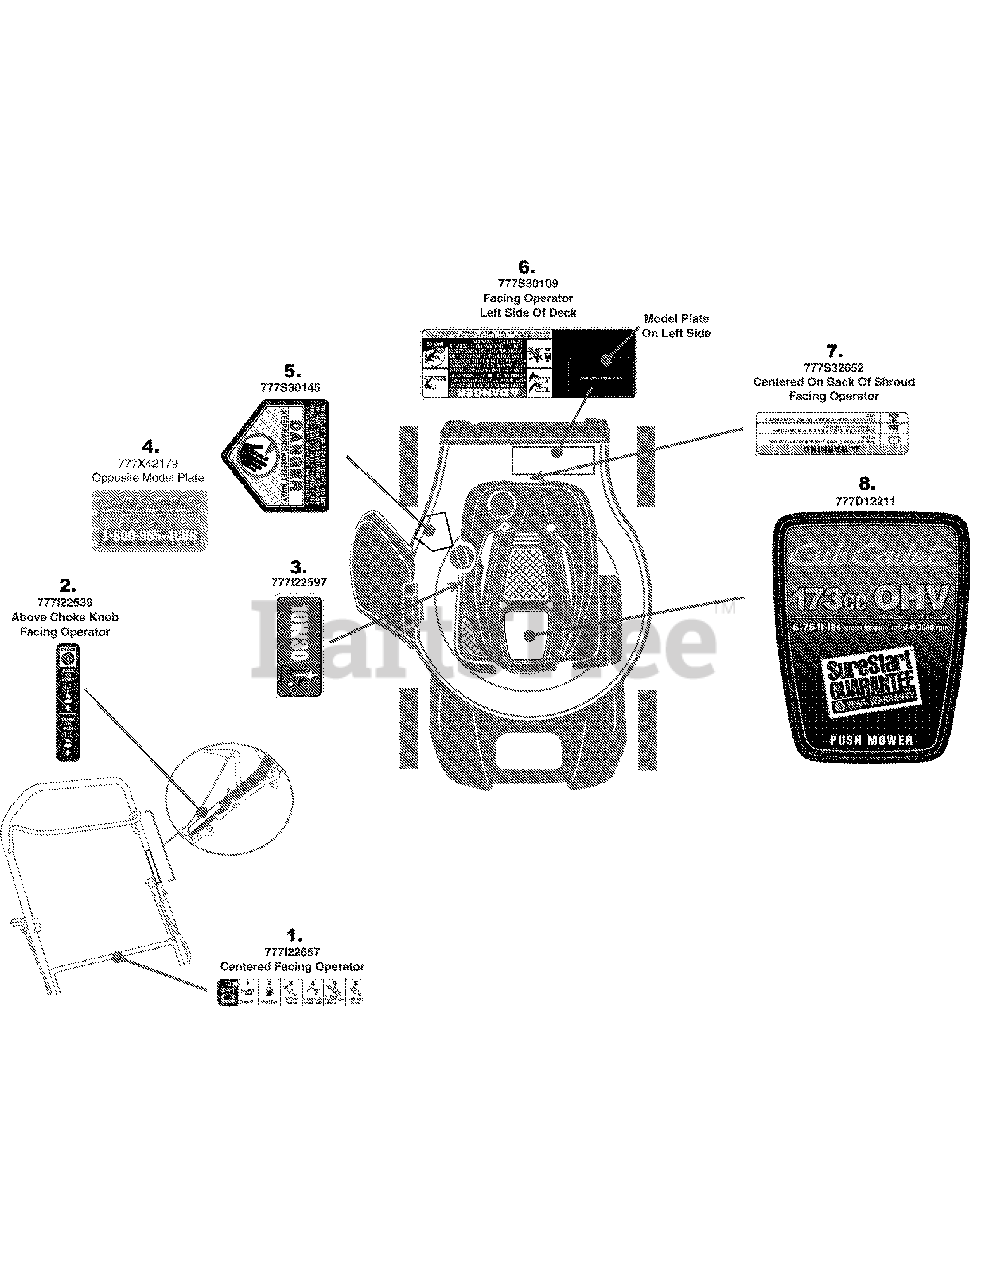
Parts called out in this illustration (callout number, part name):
1	LABEL-MOWER HANDLE
2	LABEL-MOWER HANDLE:CHOKE START/RUN
3	LABEL:MOWER SHROUD
4	LABEL
5	LABEL-CUB HOTLINE
6	LABEL-MOWER DANGER
7	LABEL:MOWER:ENGINE SHROUD
8	LABEL-173CC SHROUD OHV PUSH MWR
